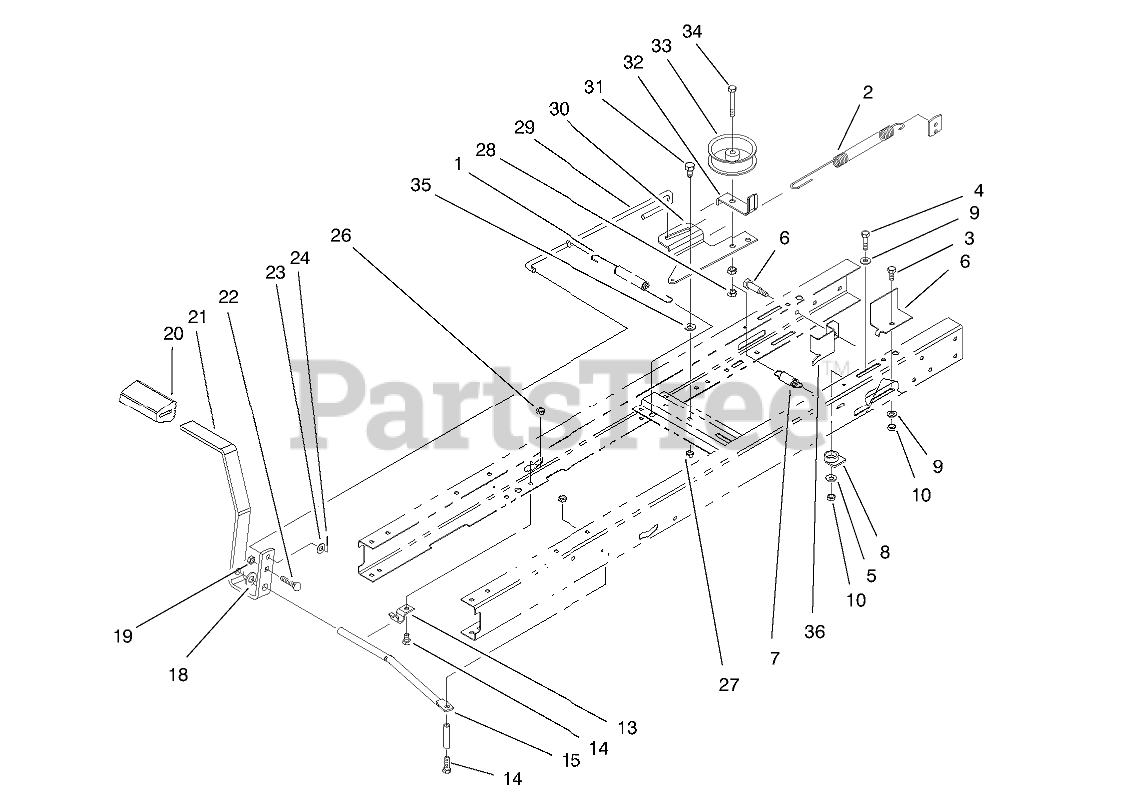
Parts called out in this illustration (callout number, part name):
1	SPRING-EXTENSION
2	SPRING-BRAKE
3	SCREW-HH
4	SCREW-HH
5	WASHER-PIVOT
6	BRACKET-BELT, GUIDE
7	SPRING-EXTENSION
8	GUIDE-CABLE
9	WASHER-PLAIN
10	NUT-LOCK, NI
13	CLAMP-PIVOT, SHIFT
14	SCREW-HH
15	ROD-PIVOT, PEDAL
18	WASHER-FLAT
19	NUT-LOCK, NI
20	PAD-PEDAL
21	PEDAL-CLUTCH/BRAKE, HYDRO
22	SCREW-CARR
23	WASHER-PLAIN
24	PIN-COTTER
26	NUT-LOCK, NI
27	NUT-LOCK, NI
28	NUT-LOCK, NI
29	ROD-CLUTCH/BRAKE
30	ARM-IDLER
31	BOLT-SHOULDER
32	GUIDE-IDLER, BELT
33	Idler Pulley
34	SCREW-HH
35	WASHER-PIVOT
36	BRACKET-BELT, GUIDE
